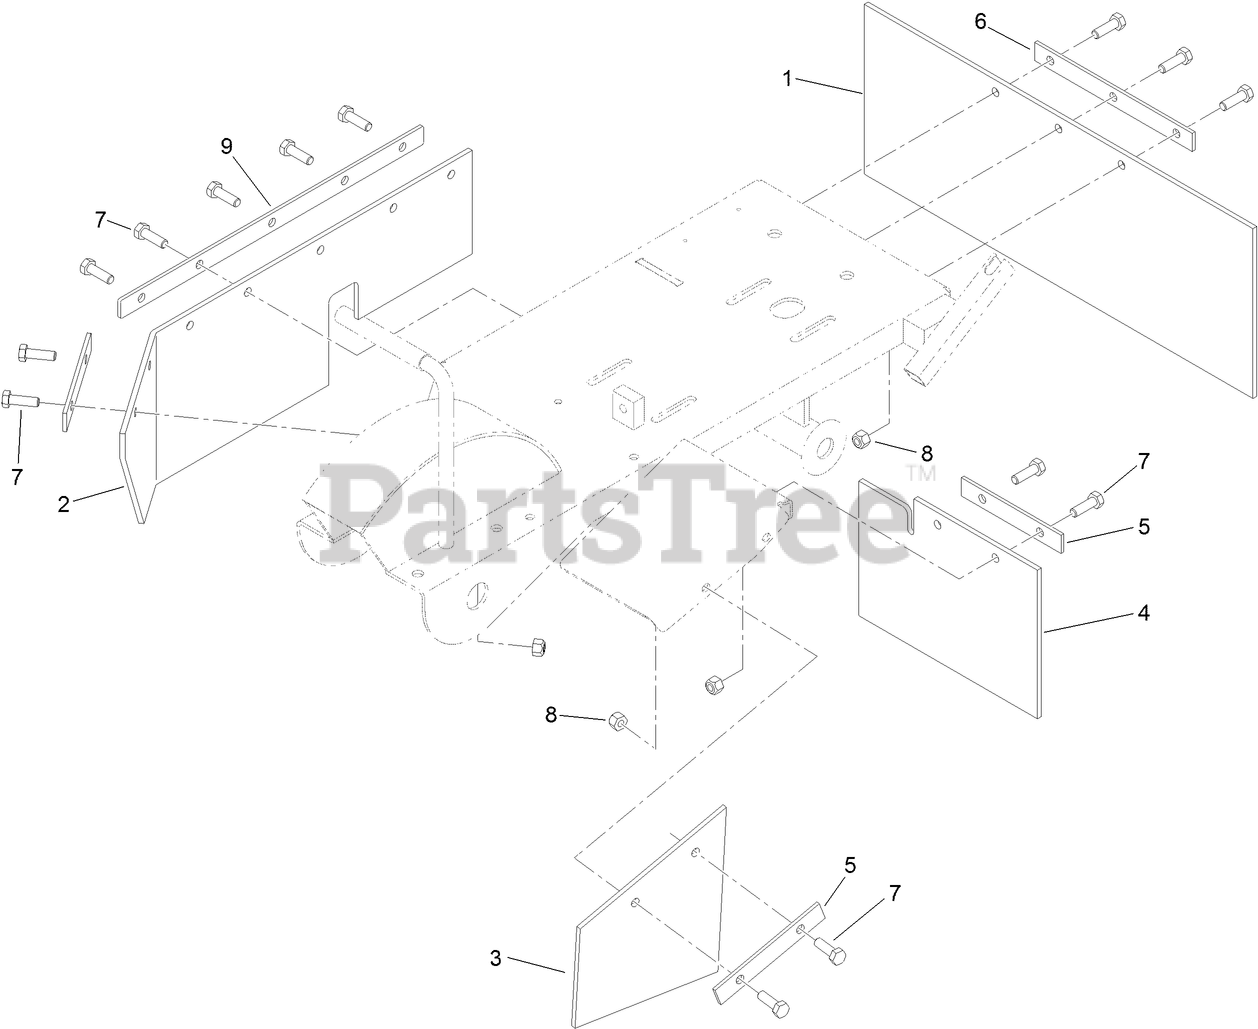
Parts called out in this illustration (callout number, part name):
1	FLAP-REAR
2	FLAP-RIGHT
3	FLAP-WING
4	FLAP-WING, REAR
5	PLATE-MOUNTING, FLAP
6	PLATE-MOUNTING, FLAP (REAR)
7	SCREW-HH
8	NUT-LOCK, NI
9	PLATE-MOUNTING, FLAP
